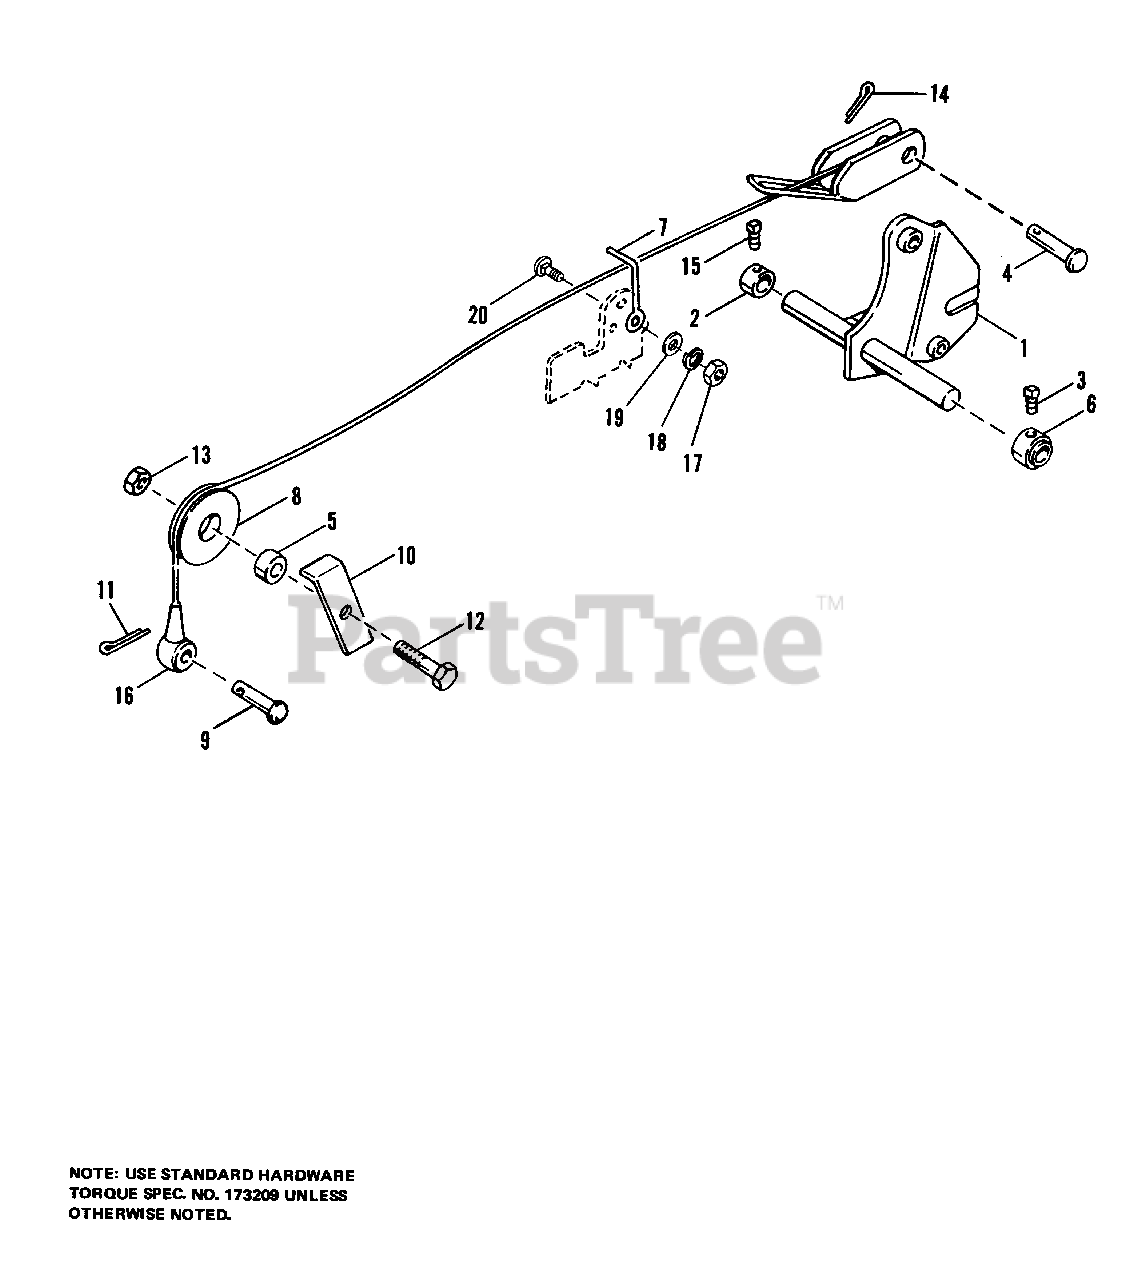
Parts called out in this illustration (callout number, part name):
1	LEVER ASSY, Lift
2	COLLAR, Set
3	SETSCREW, Sq. Hd., 5/16-18 x 5/8
6	COLLAR, Set
7	STOP, Belt
9	PIN
10	GUARD, Cable
11	PIN, Cotter, 3/32 x 1
12	CAPSCREW, Hex Hd., 3/8-16 x 1-1/4
13	NUT, Hex Jam, 3/8-16
14	PIN, Cotter. 1/8 x 1
15	SETSCREW, Sq. Hd., 5/16-18 x 3/8
16	CABLE ASSY, Lift
17	NUT, Hex, 1/4-20
18	LOCKWASHER, Spring, 1/4
19	WASHER, Plain, 1/4
20	BOLT, Rd Hd., Sq. Nk,, 1/4-20 x 3/4
